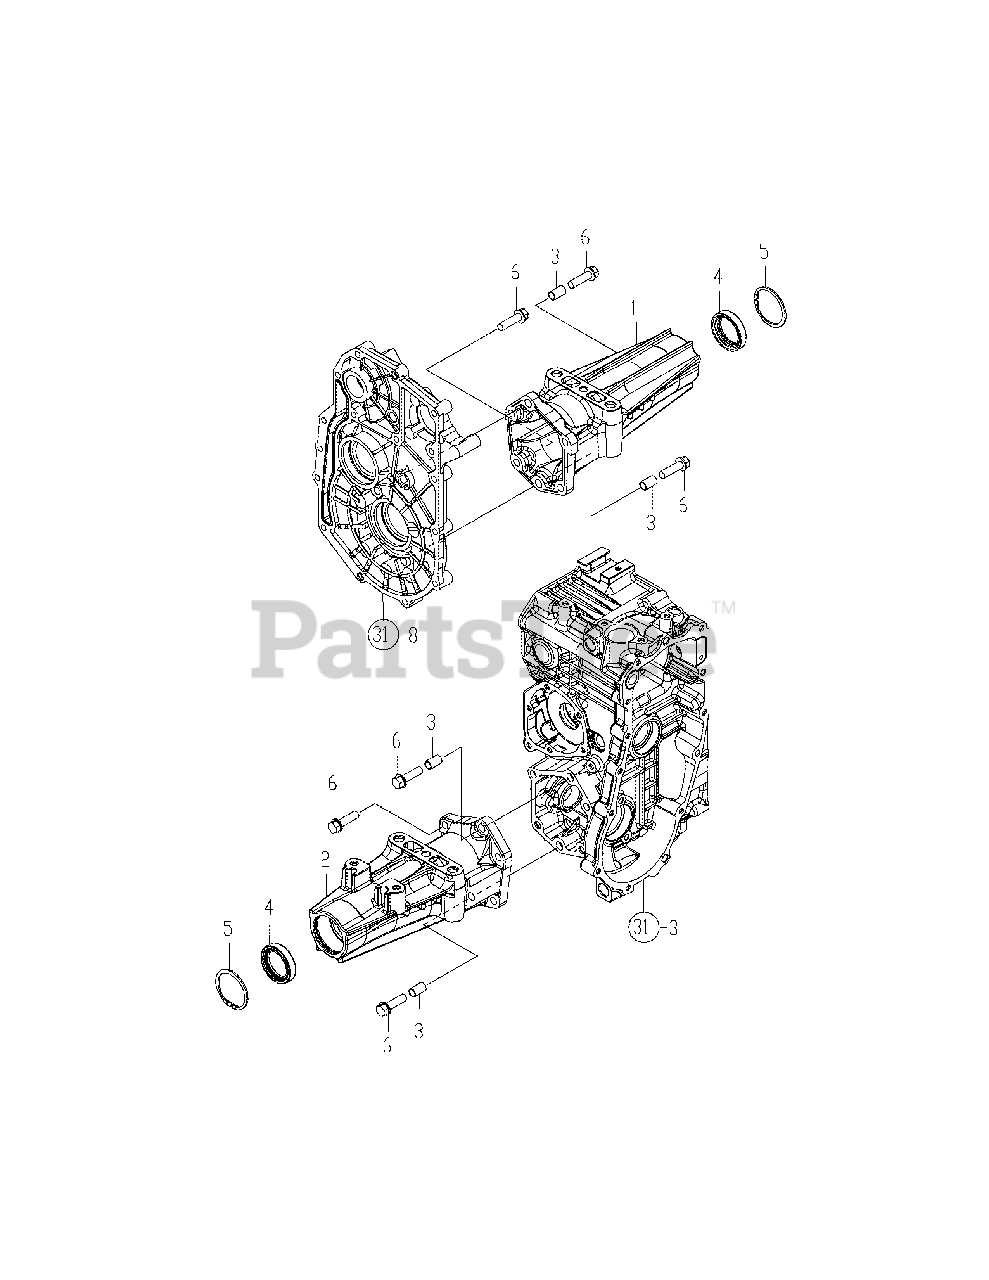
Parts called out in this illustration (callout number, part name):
1	Housing, Rear Axle R
2	Housing, Rear Axle
3	Collar, 10X12X20
4	Seal, Tc395511
